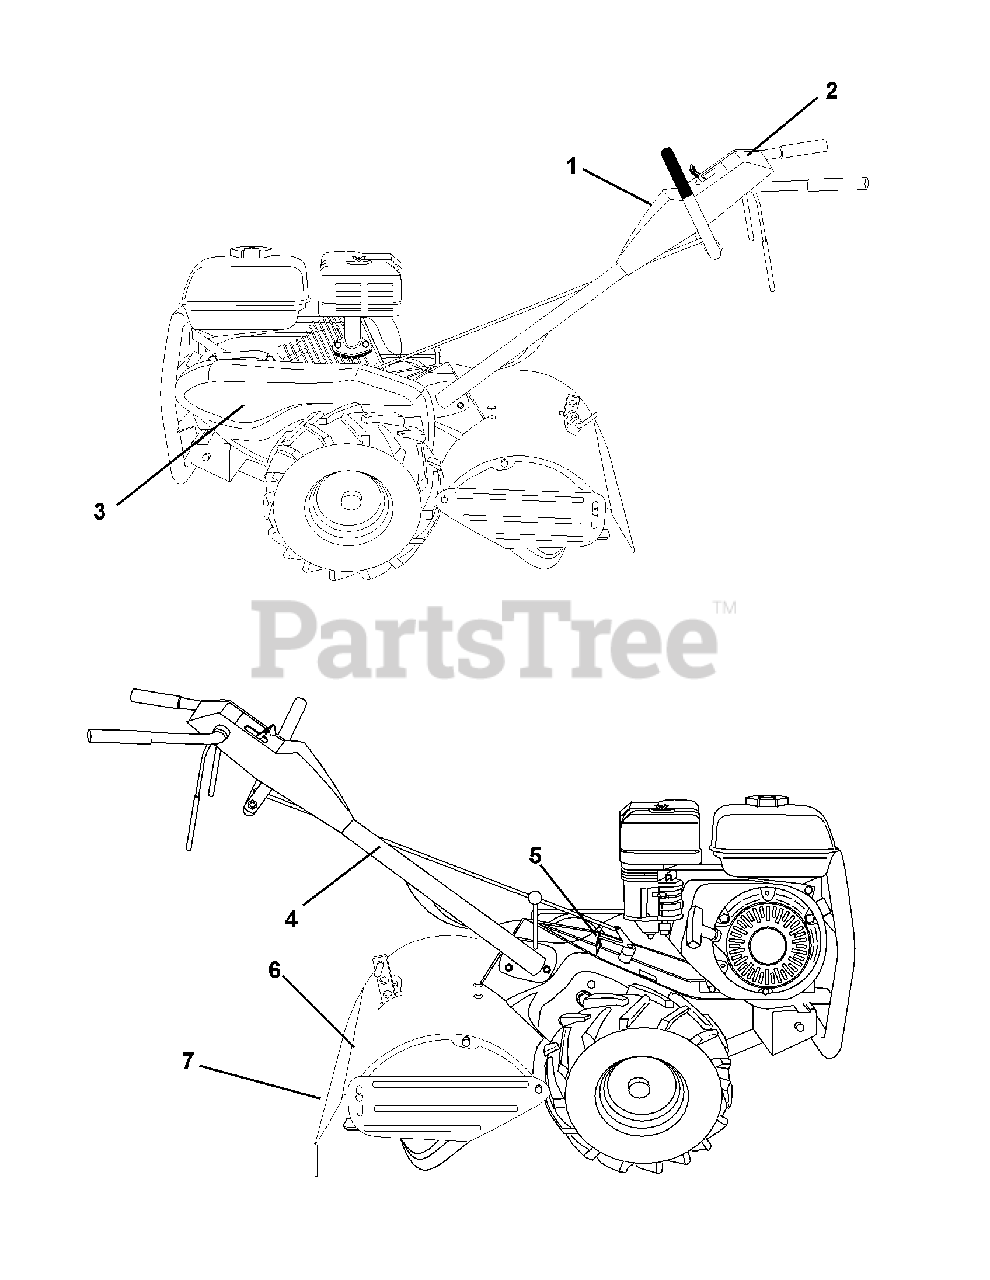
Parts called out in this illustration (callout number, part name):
1	Decal, Logo
2	Decal, Logo
3	Decal, Logo
4	Decal, Hand Placement
5	Decal, Shift Indicator
6	Decal, Warning Till
7	Decal, Warning, Rotating Tines
